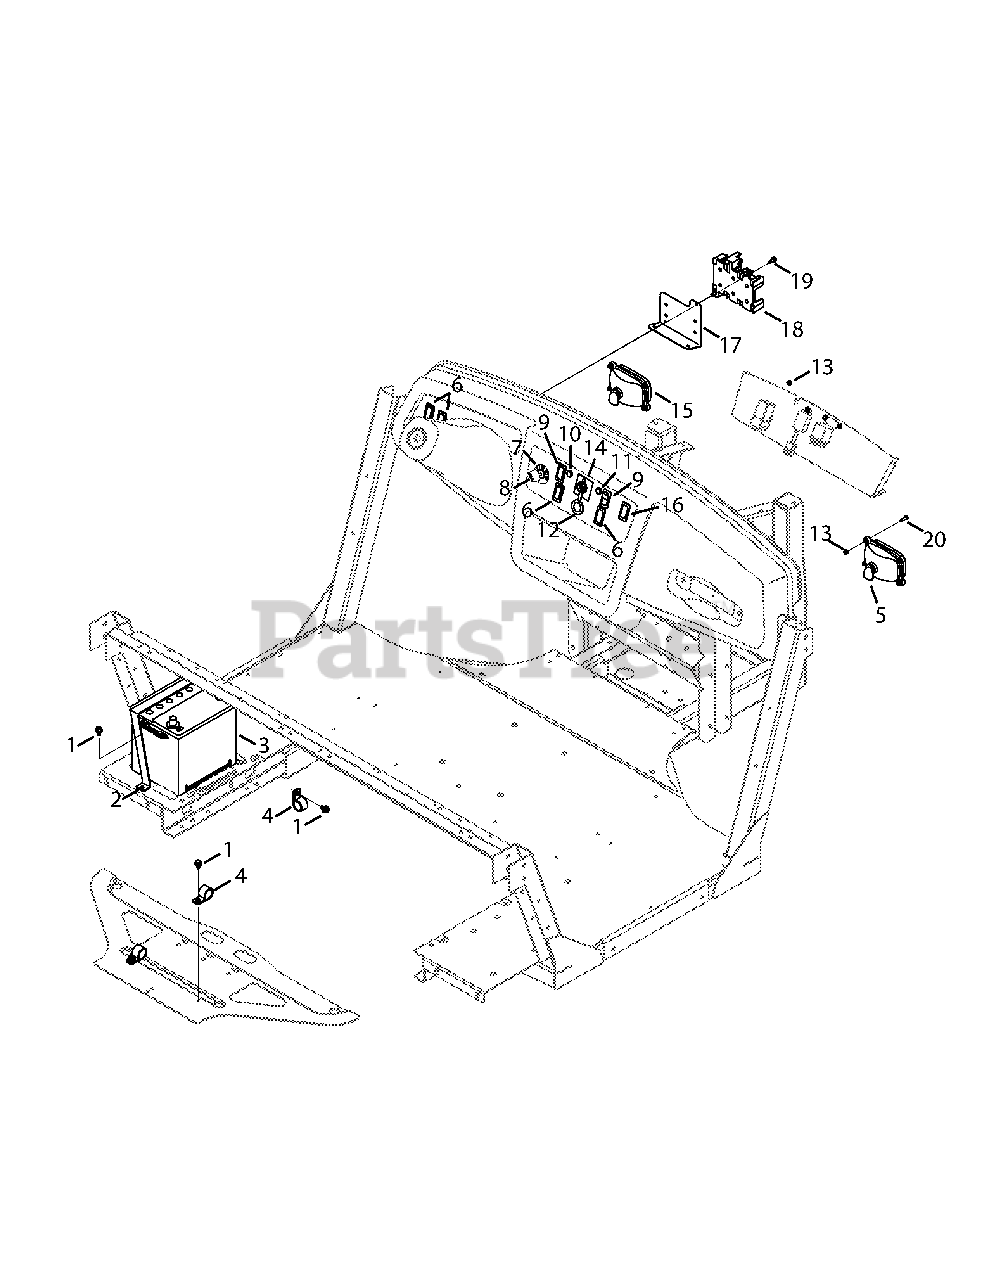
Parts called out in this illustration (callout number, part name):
1	Screw, TT, 5/16-18 x .500
2	Bracket, Mt., Battery
3	Battery, 450 CCA Wet
5	Head lamp Bulb
6	Panel, Plug, Switch
7	Switch, Key, 4 Pos. Delta
8	Key, Delta, Plastic
9	Switch, 4x4, Rocker
10	Lamp, Ind., Green, Incandescent
11	Lamp, Ind., Red, Incandescent
12	Receptacle, Power, 12v
13	Nut, Hex Lock, #10-24
14	Meter, Ind., Hour Flat Face
15	Headlight Assembly (Incl. # 21)
16	Seat Belt Indicator
17	Bracket, Fuse Mount
18	Relay, Holder, 3-Way
19	Screw, TT, 1/4-20 x .500
20	Screw, TT, #10-24 x .750
